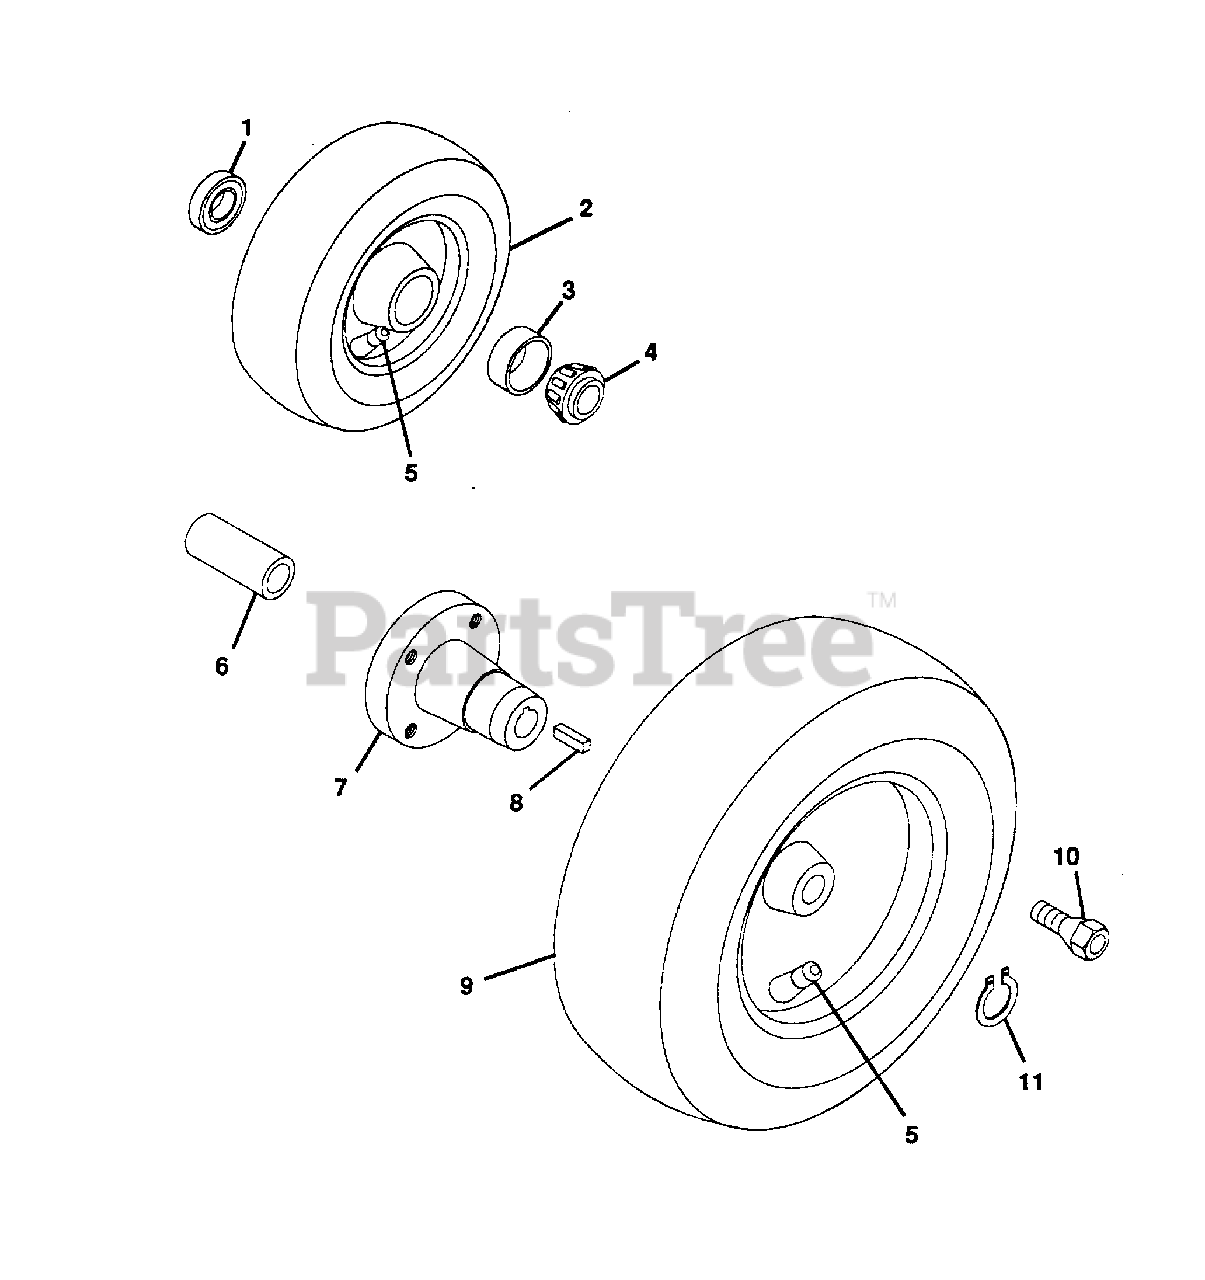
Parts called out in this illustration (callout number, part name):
1	SEAL, WHEEL
2	ASSEMBLY, WHEEL REAR
3	BEARING, CUP
4	BEARING, CONE
5	ASSEMBLY, VALVE STEM
6	SPACER
7	HUB
8	KEY, SQUARE .250X1.250
9	ASSEMBLY, WHEEL
10	STUD, WHEEL
11	RING, RETAINING
